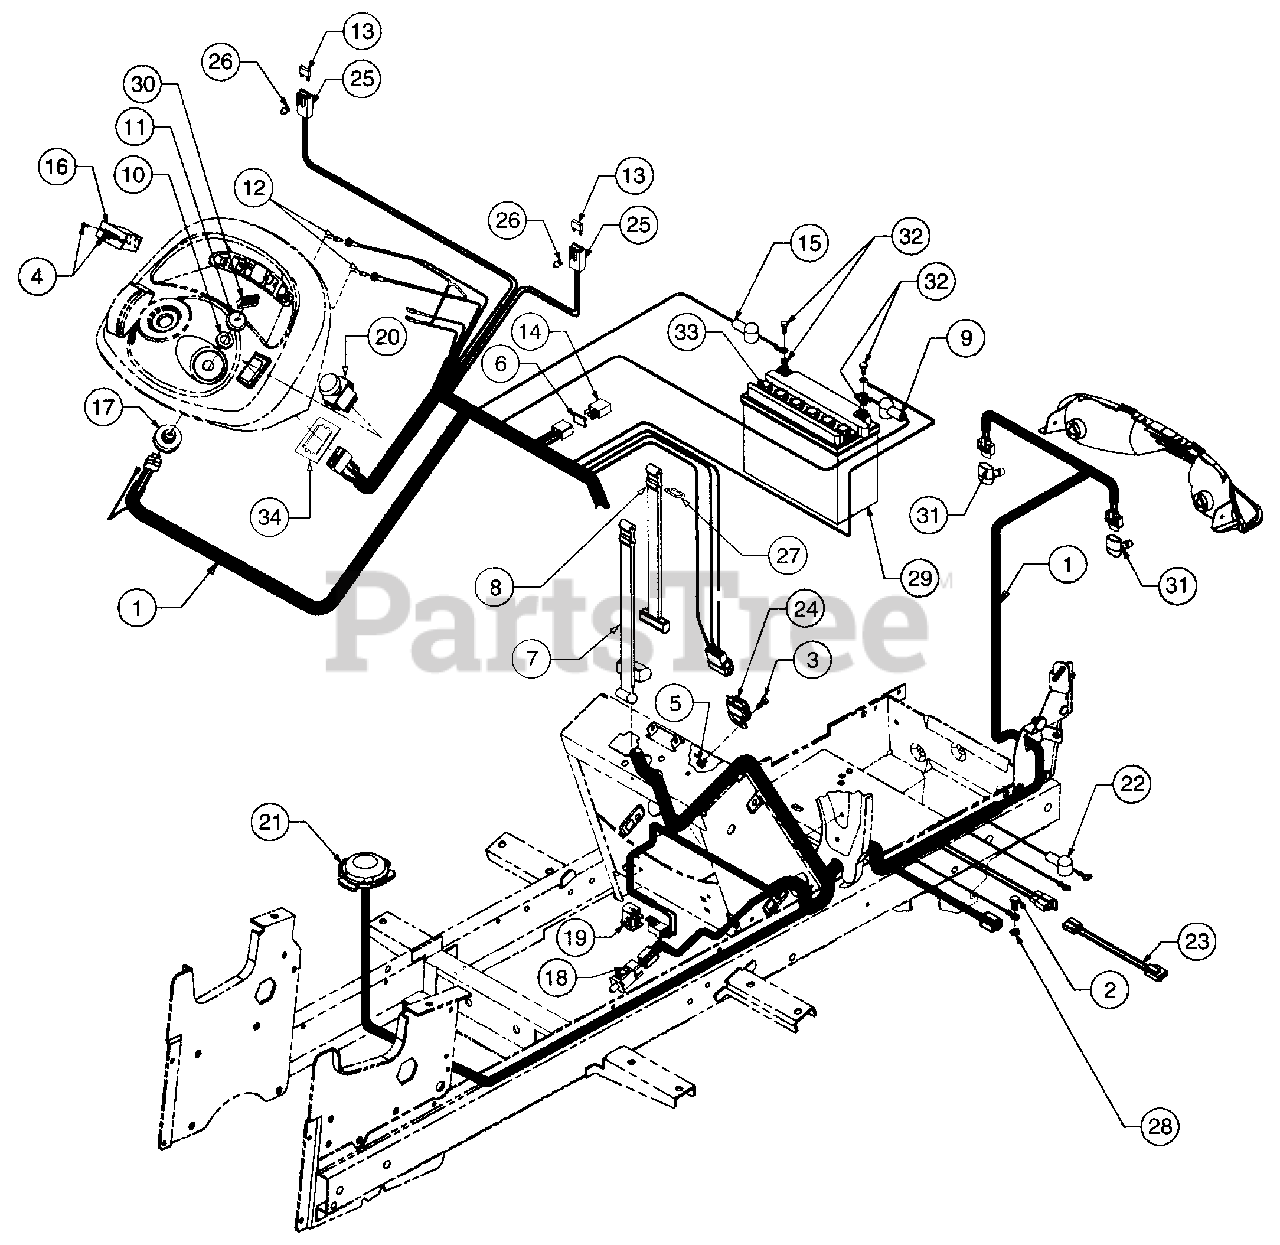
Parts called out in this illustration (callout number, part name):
1	Wire Harness, Main
2	Screw, Hex Cap, 5/16-24 x .62
3	Screw, Hex Cap, 1/4-20 x .625
4	Screw, Truss Hd Tapp, #6 x .62
5	Nut, Hex Sems, 1/4-20
6	Gasket, Silicone
7	Strap, Battery Retainer
8	Strap, Battery Retainer
9	Cover, Terminal Black
10	Nut, Ignition Switch
11	Cap, Ignition Switch
12	Bulb, Indicator
13	Fuse, 20 Amp
14	Relay
15	Cover, Terminal Red
16	Hour Meter
17	Switch, Ignition
18	Switch, Interlock
19	Switch, Snap Mount - Normally Closed
20	Switch, PTO
21	Switch, Seat
22	Cover, Terminal Red
23	Adapter, PTO Harness
24	Module, Voltage Sensor
25	Holder, Fuse
26	Clip, Fuse Holder Mounting
27	Hook, Wire Rectangular
28	Washer, External Lock, 5/16
29	Battery
30	Key, Ignition
31	Bulb, Head Lamp
32	Battery Cable Hardware
33	Cap, Battery
34	Bracket, PTO Switch Retainer
